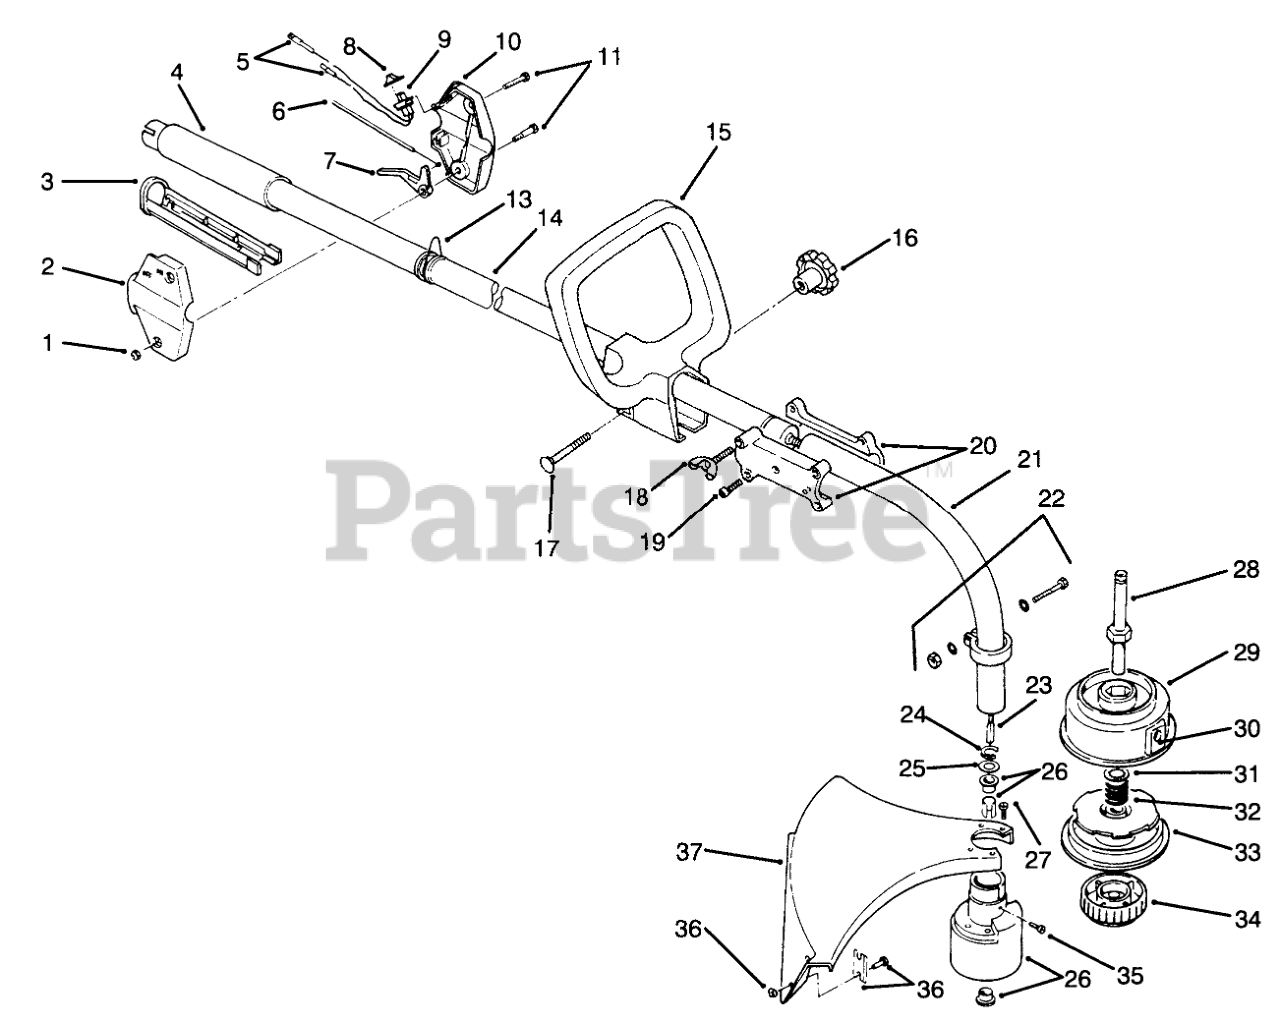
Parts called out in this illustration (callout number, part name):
1	NUT-LOCK, NI
2	HOUSING RH
3	TROUGH 1"
4	GRIP - RUBBER
5	LEAD WIRE ASM
6	THROTTLE CABLE
7	THROTTLE LEVER
8	SWITCH COVER
9	SWITCH
10	HOUSING LH
13	Clip-Shoulder Strap
14	UPPER DRIVE HSG ASM
15	HANDLE SECONDARY
17	BOLT-CARRIAGE
18	Adjustment knob
19	COUPLING BOLT ASM
20	Coupling-Split Boom
21	LOWER DRIVE HSG ASM
22	CLAMP ASM - UPPER
23	Drive Shaft
24	RETAINING RING
25	WASHER
26	BUSHING HSG ASM
27	GUARD MTG SCREW ASM
28	Shaft-Spool
29	OUTER SPOOL EYELET ASM
30	EYELET
31	RETAINER WASHER(SET OF 10)
32	REEL - INNER
33	SPRING
34	SMALL BUMP KNOB ASM
35	ANTI-ROTATION SCREW
36	Assy.-Blade(Incl. 2 Screws & 2 Nuts)
37	Assembly-Guard & Blade(Incl. Ref. No.36)
